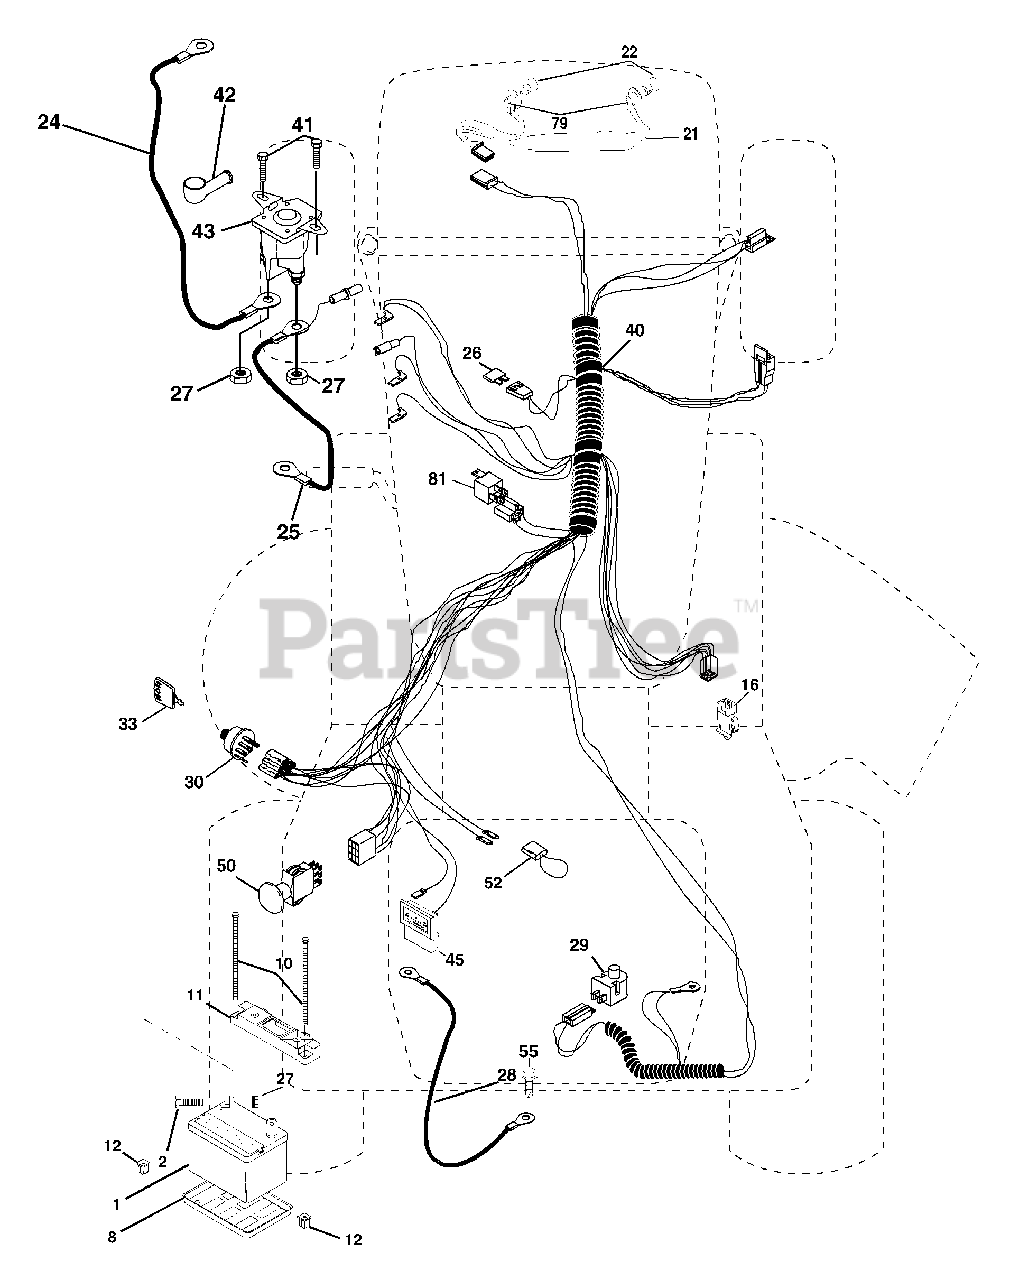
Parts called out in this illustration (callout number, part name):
1	Battery
2	Bolt Hex Hd 1/4-20 UNC X 3/4
8	Tray, Battery
10	Bolt, BTR FRT 1/4-20 x 7.5
11	Hold Down Battery, Front
12	Nut, Push, Nylon
16	Switch Interlock Push-In
21	Harness Asm Light W/4152j
22	Bulb Light
24	Cable Battery
25	Cable Batterywire
26	Fuse
27	Nut Keps Hex 1/4-20 Unc
28	Cable Ground
29	Switch Plunger Normal OP Olive
30	Switch Ign 4 pos w/lights
33	Key Ign
40	Harness Ign.
41	Bolt Blk Fin Hex 1/4-20 x 1/2
42	Cover Terminal Red
43	Solenoid
45	Ammeter Rectangular
50	Switch, PTO
52	Protection wire Loop (Hour Meter)
55	Screw Thdrol 5/16-18 x 1/2
79	Socket Asm
81	Relay Asm
